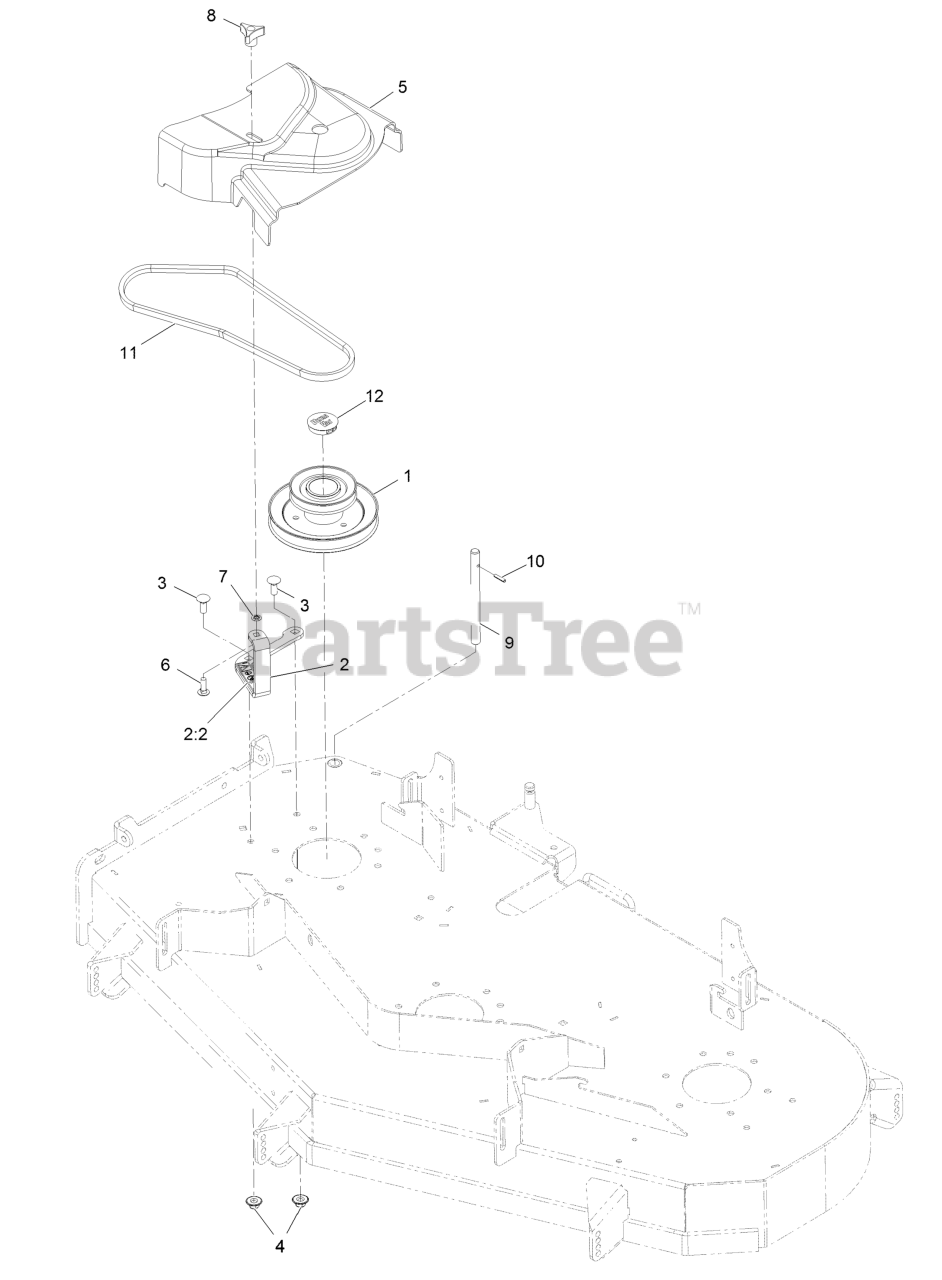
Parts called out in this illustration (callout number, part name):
1	Jackshaft-Uv Drive 523
2	ASM-Cvr Brkt W/Decal
2:2	Decal-Danger
3	Bolt-CARR
4	Nut-Flange, NI
5	Cover-Belt, Uv 52
6	Bolt-CARR
7	Ring-Retaining, Bolt
8	Knob-3 Prong
9	Shaft-Catcher, Grass
10	Pin-Roll
11	Belt, Blower Drive 52
